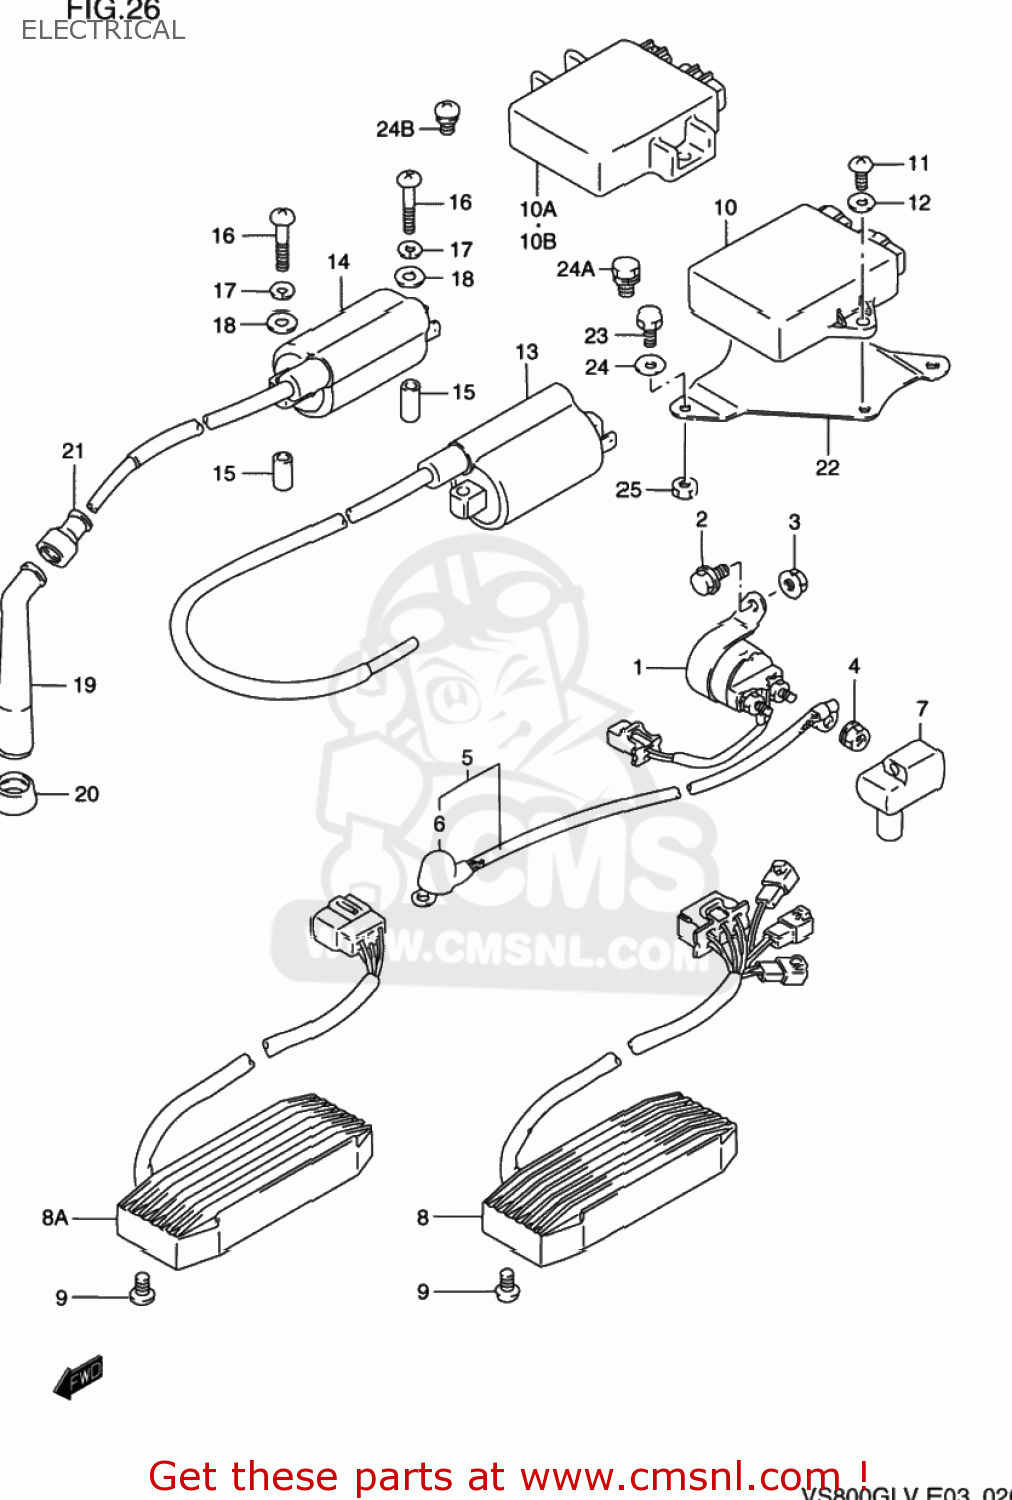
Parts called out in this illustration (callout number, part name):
1	RELAY ASSY,STARTING MOTOR
2	BOLT
3	NUT
4	NUT
5	WIRE,STARTER MOTOR LEAD
6	CAP,STARTER MOTOR LEAD
7	CAP,STARTER RELAY
8	RECTIFIER ASSY
8A	RECTIFIER ASSY
9	BOLT
10	IGNITER UNIT ASSEMBLY
10A	IGNITER ASSEMBLY
10B	IGNITOR ASSY
11	SCREW
12	WASHER
13	COIL ASSY,IGNITION
14	COIL ASSY,IGNITION
15	SPACER(6.4X10X19)
16	SCREW (5X38)
17	LOCK WASHER
18	WASHER
19	CAP,SPARK PLUG
20	SEAL,SPARK PLUG CAP
21	SEAL,HIGH TENSION CORD
22	PLATE,IGNITOR FITING
23	BOLT
24	LOCK WASHER
24A	BOLT
24B	BOLT
25	NUT
